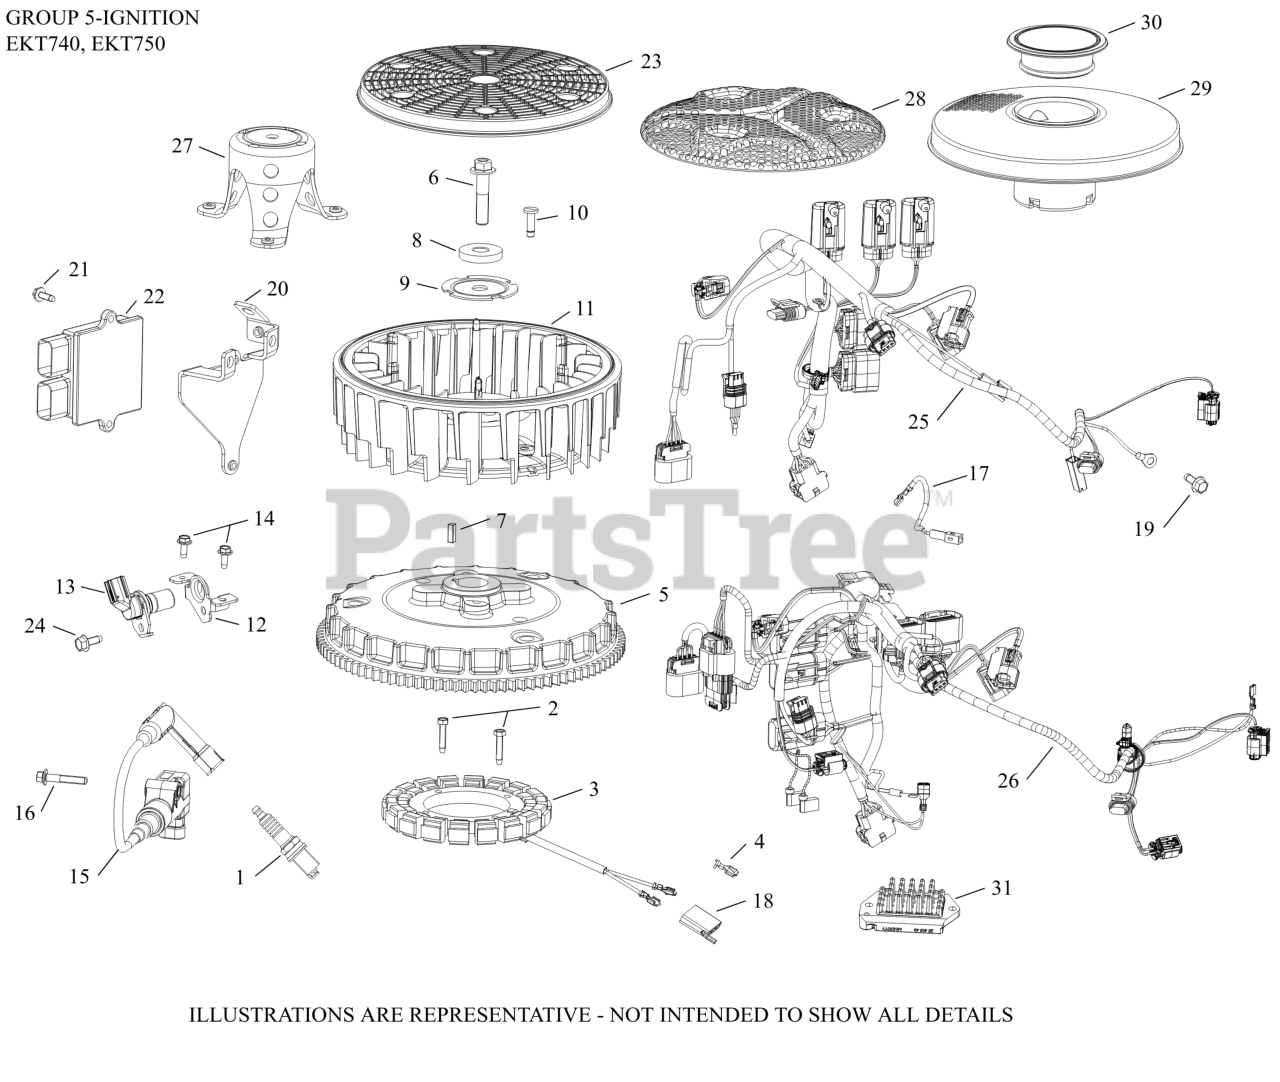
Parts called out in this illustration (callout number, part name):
1	SPARK PLUG, RFI
2	SCREW, THREAD FORMING
3	KIT, 15 / 20 AMP STATOR
5	FLYWHEEL, ASSEMBLY
6	SCREW, HEX FLANGE
7	KEY, SQUARE
8	WASHER, FLAT
9	PLATE, FAN MOUNTING
10	RETAINER, FLYWHEEL FAN
12	BRACKET, SENSOR
13	SENSOR, SPEED
14	SCREW, FLG THD FRM M5X0.8X13
15	COIL, IGNITION - EFI (RFI/EMC)
16	SCREW, FLG (BLACK) M6X1.0X34
17	LEAD, REGULATOR RECTIFIER JUMPER
18	CONNECTOR
19	SCREW, CAPTIVE WASHER (SEMS)
20	BRACKET, ECU
21	SCREW, THREAD FORMING
22	MODULE, ECU
23	SCREEN, GRASS
24	SCREW, THREAD FORMING
25	HARNESS, WIRING ASSEMBLY (RECOIL)
